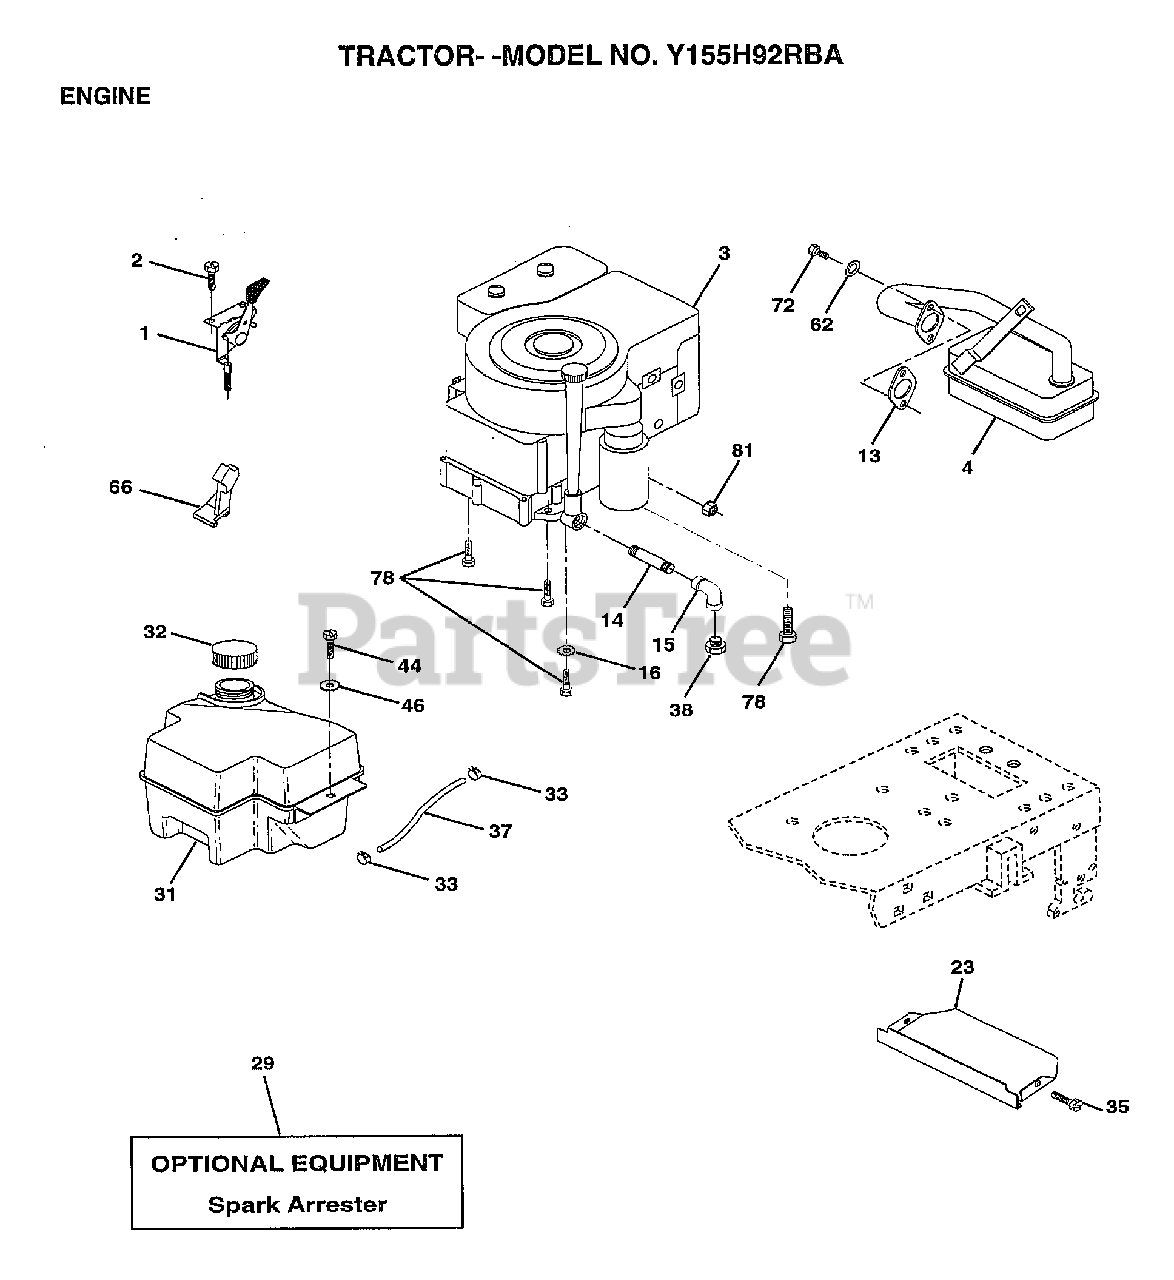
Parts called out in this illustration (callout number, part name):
1	CONTROL.THTL.23.5
2	SCREW LT
4	MUFFLER
14	PIPE NIPPLE
15	ELBOW
16	LOCKWASHER
23	SHIELD.BRN/DBR.GD
31	TANK.FUEL.FRONT.
32	CAP ASM FUEL
33	HOSE CLAMP
35	SCREW
37	LINE FUEL
44	SCREW HEX CRT
46	WASHER
62	LOCKWASHER
66	"STOP,DASH THROTT"
72	SCREW
78	SCREW
81	NUT
